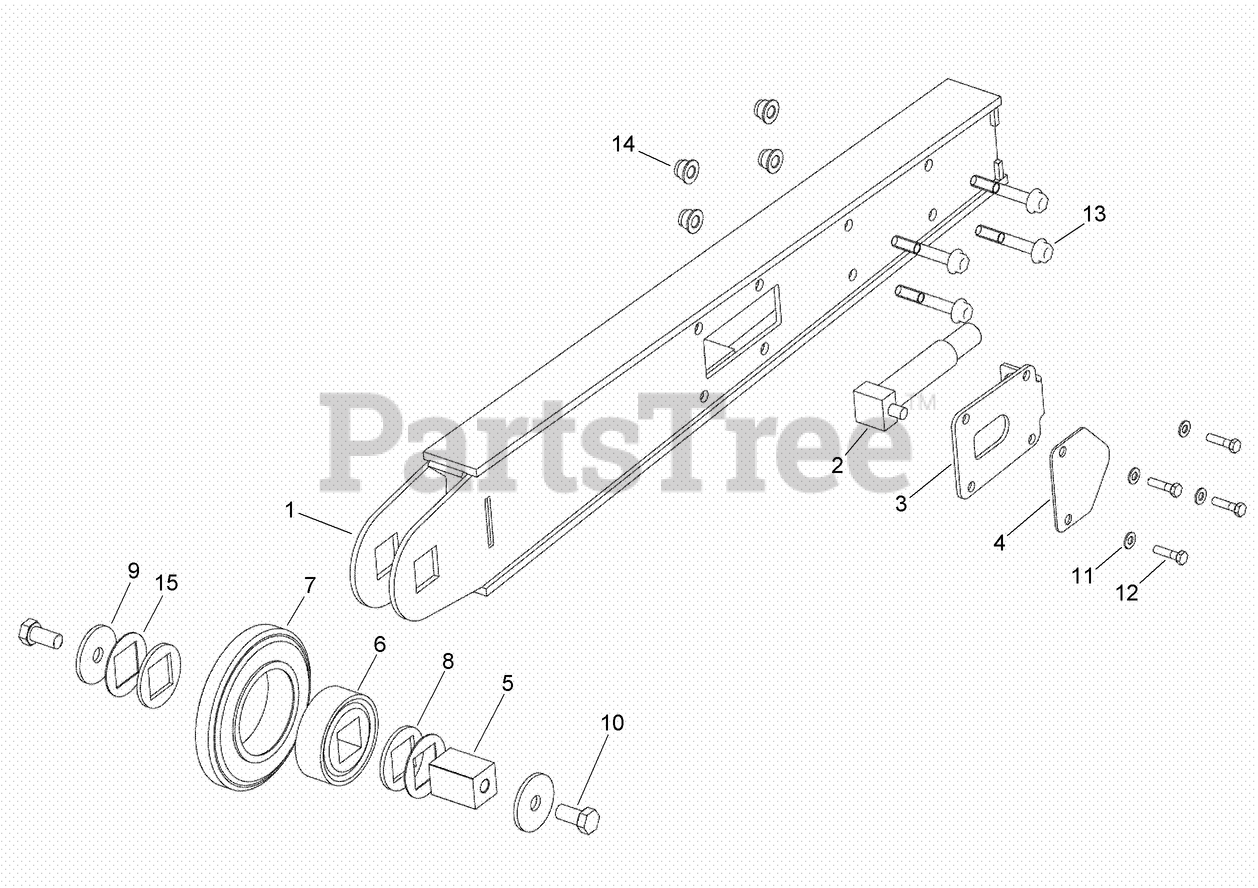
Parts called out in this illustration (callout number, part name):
1	BOOM - 36in Rock
2	PISTON-ADJ
3	PLATE - Piston Keeper
4	PLATE - Cover
5	MOUNT-SHAFT, IDLER
6	BEARING
7	WHEEL-BOOM END, IDLER
8	WASHER
10	BOLT - Hex Hd .625 x 1.25 GR5 ZND
11	WASHER-FLAT
12	BOLT-Hex, 5/16 NC x 1-1/4 inch
13	SCREW-HHF
14	NUT-HHF, LOCK
